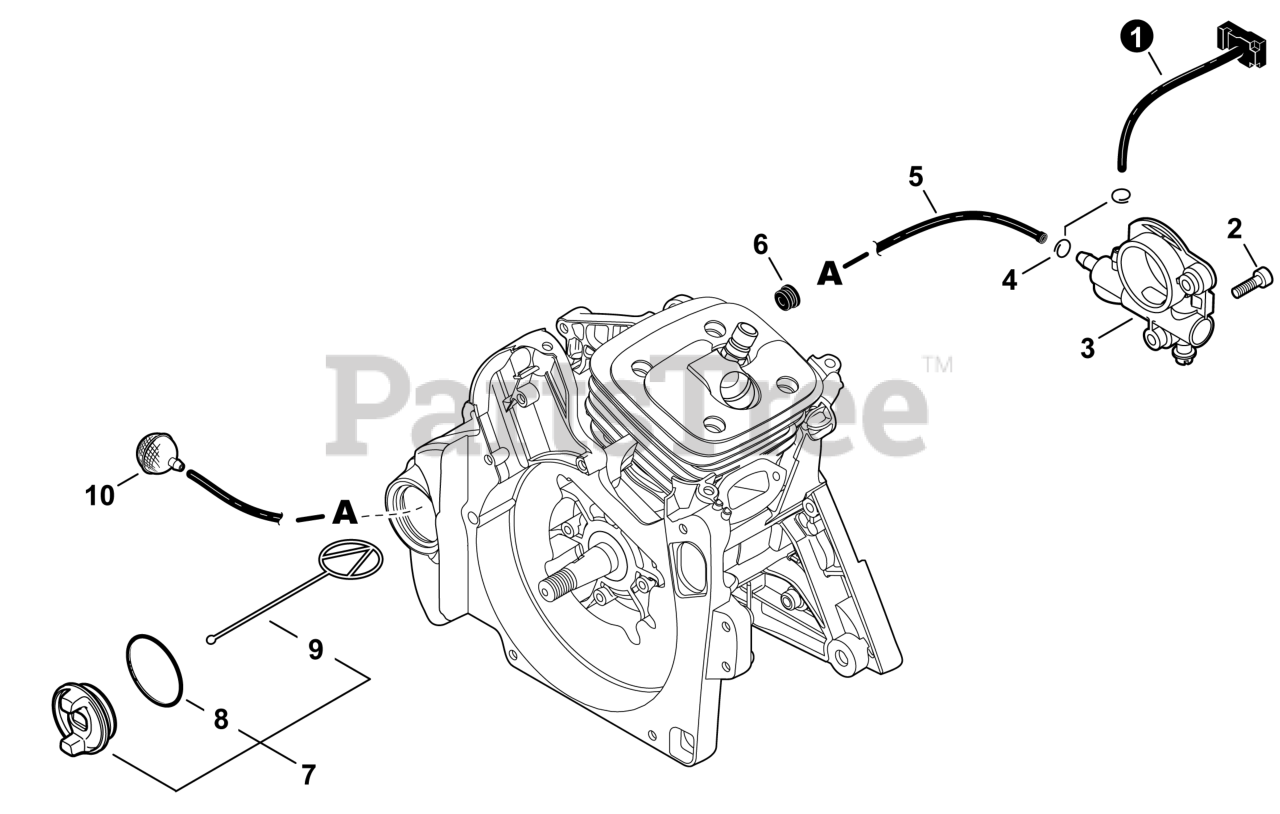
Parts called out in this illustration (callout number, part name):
1	PIPE, OIL
2	BOLT, TORX 4x12
3	AUTO-OILER ASSY
5	PIPE, FUEL 3x6x210 BLACK
7	CAP ASSY, OIL
8	O-RING 29
9	CONNECTOR, CAP L= 60 MM
10	FILTER, OIL
